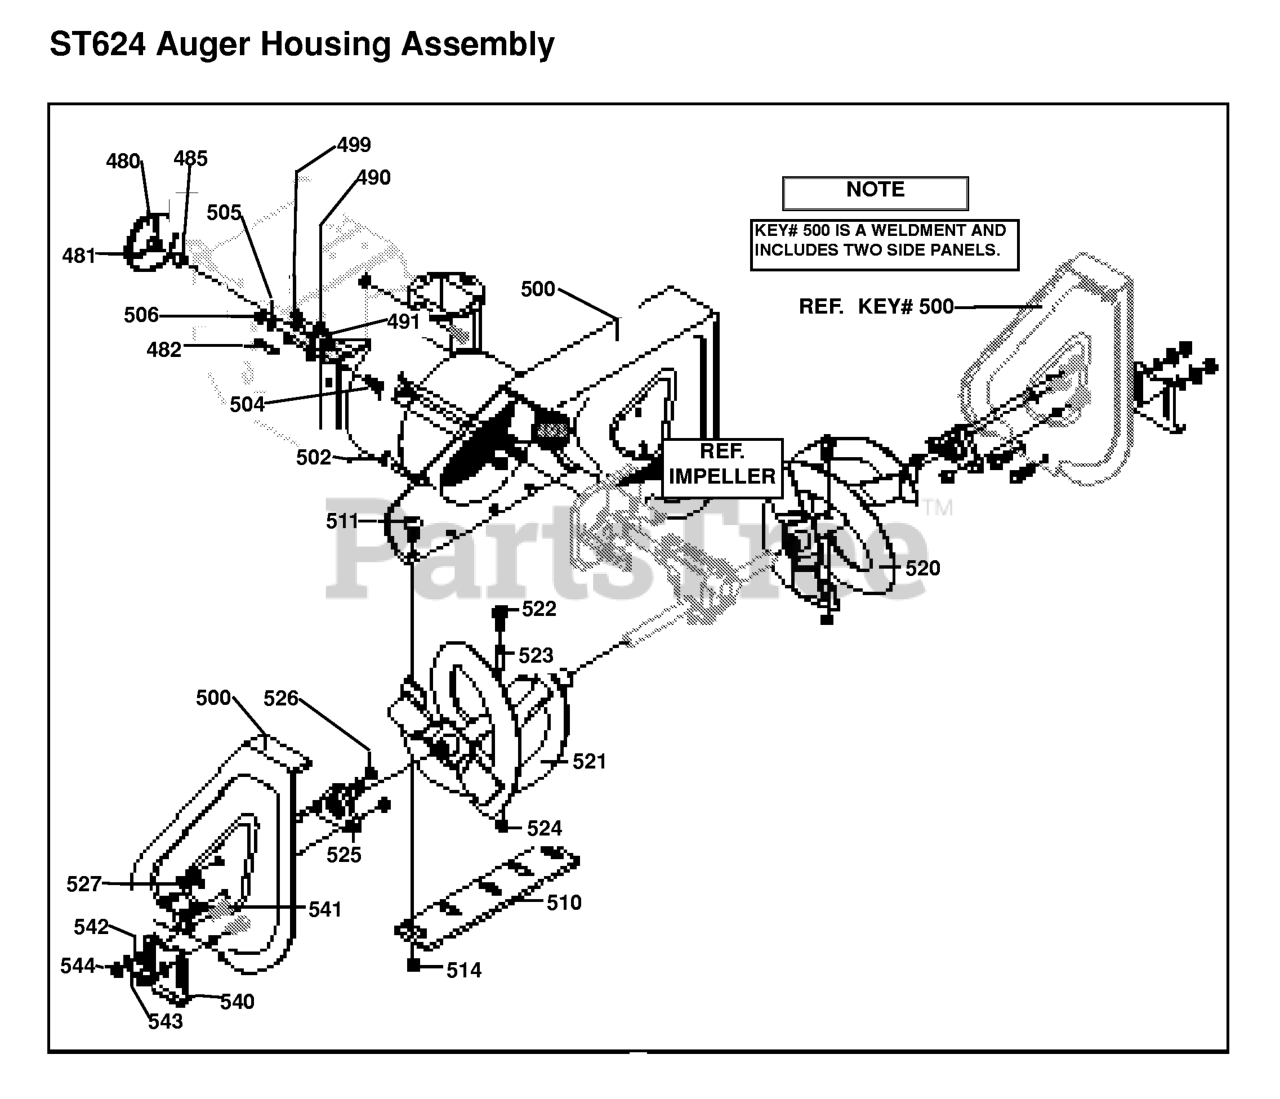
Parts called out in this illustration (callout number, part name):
480	PULLEY, V4L
481	SCREW, 5/16-18 X .63
482	SQUARE KEY
485	SPACER, SLEV .676X1.00X.53
491	BEARING
493	SCREW, 5/16-18X .75 HHC
499	NUT, 5/16-18
500	HOUSING, ASSY
502	RATCHET FASTENER
505	WASHER, REGSPTLK.393X.68X
506	NUT, 3/8-16 REGHXCTRLK
510	SCRAPER BLADE
511	CARRIAGE BOLT
514	Nut, 1/4-20 Whiz-loc
520	AUGER, ASSY LH
521	AUGER, ASSY RH
522	BOLT, SHEAR 703057
525	Bearing, Flange
526	Nut, 5/16-18, HXWDFLLK
527	SCREW, 5/16-18X.75
540	SKID, HEIGHT ADJUST
542	WASHER, FLAT .344X .69X.
543	WASHER, HVSPTLK .328X.60X
544	NUT, 5/16-18 REGHEX
